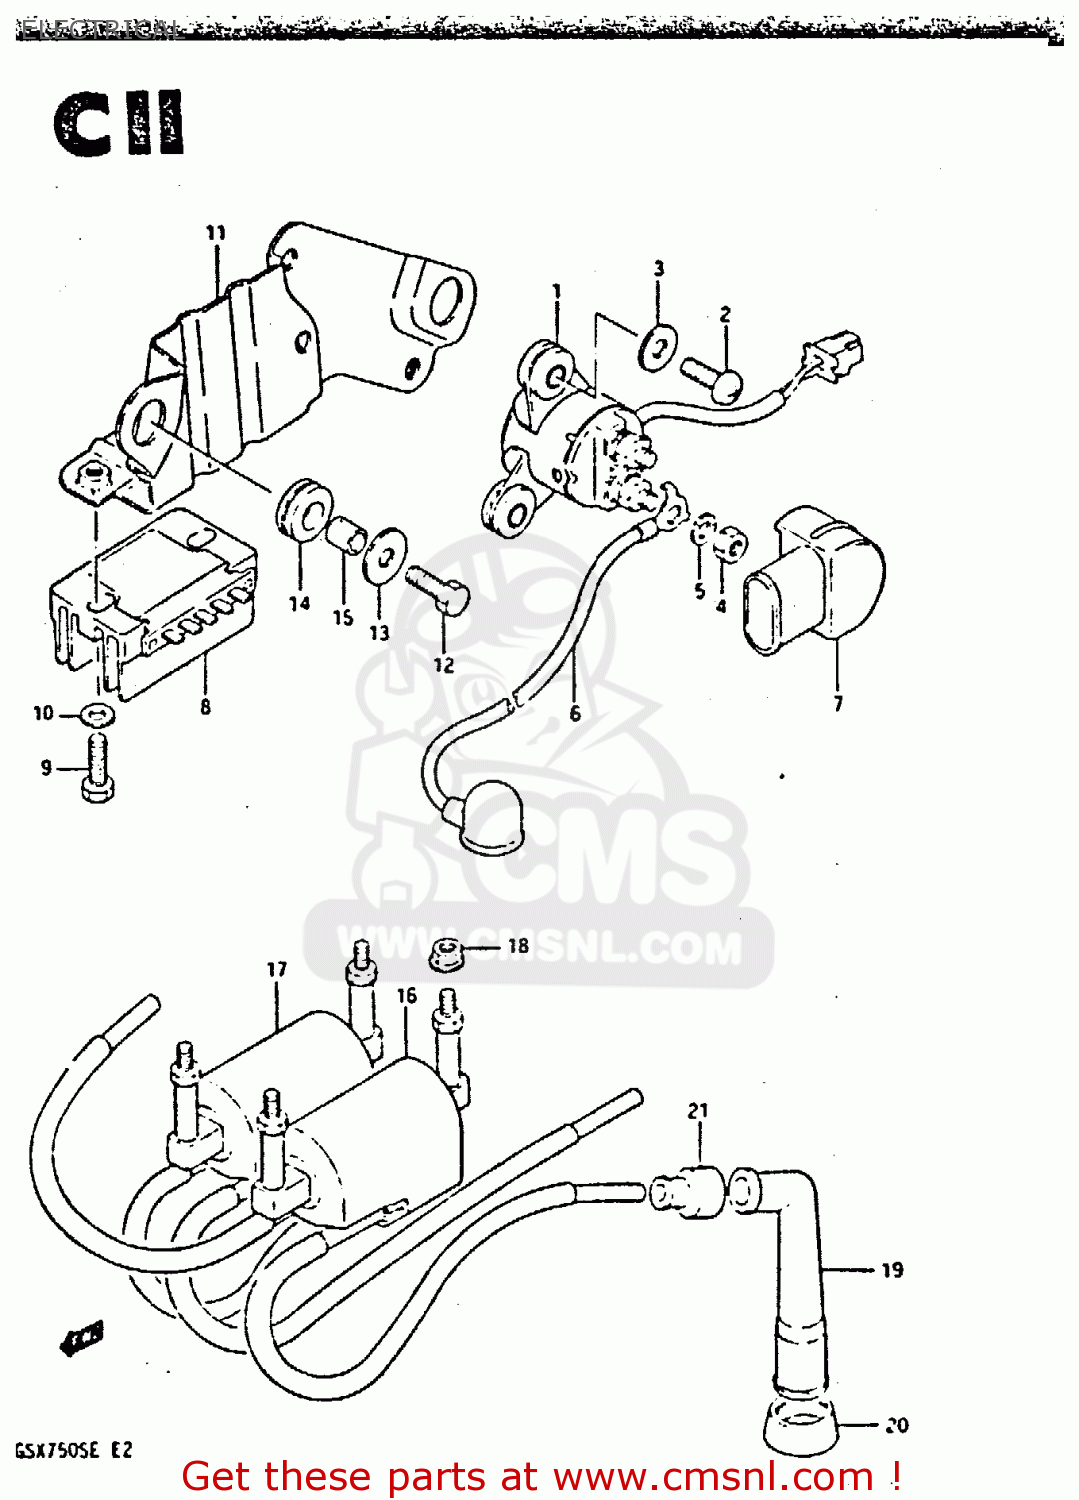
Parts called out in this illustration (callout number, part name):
1	RELAY ASSY,STARTING MOTOR
2	SCREW
3	WASHER
4	NUT
5	WASHER,LOCK
6	LEAD WIRE, STARTING MOTOR
7	CAP,STARTER RELAY TERMINAL
8	RECTIFIER ASSEMBLY
9	BOLT(6X20)
10	WASHER
11	PLATE, PARTS HOLDER
12	BOLT
13	WASHER (6.5X20X1.2)
14	CUSHION
15	SPACER(6.1X9X7.5)
16	COIL ASSEMBLY,IGNITION
17	COIL ASSEMBLY,IGNITION NO
18	NUT
19	CAP,SPARK PLUG
20	SEAL,SPARK PLUG CAP
21	SEAL,SPARK PLU
